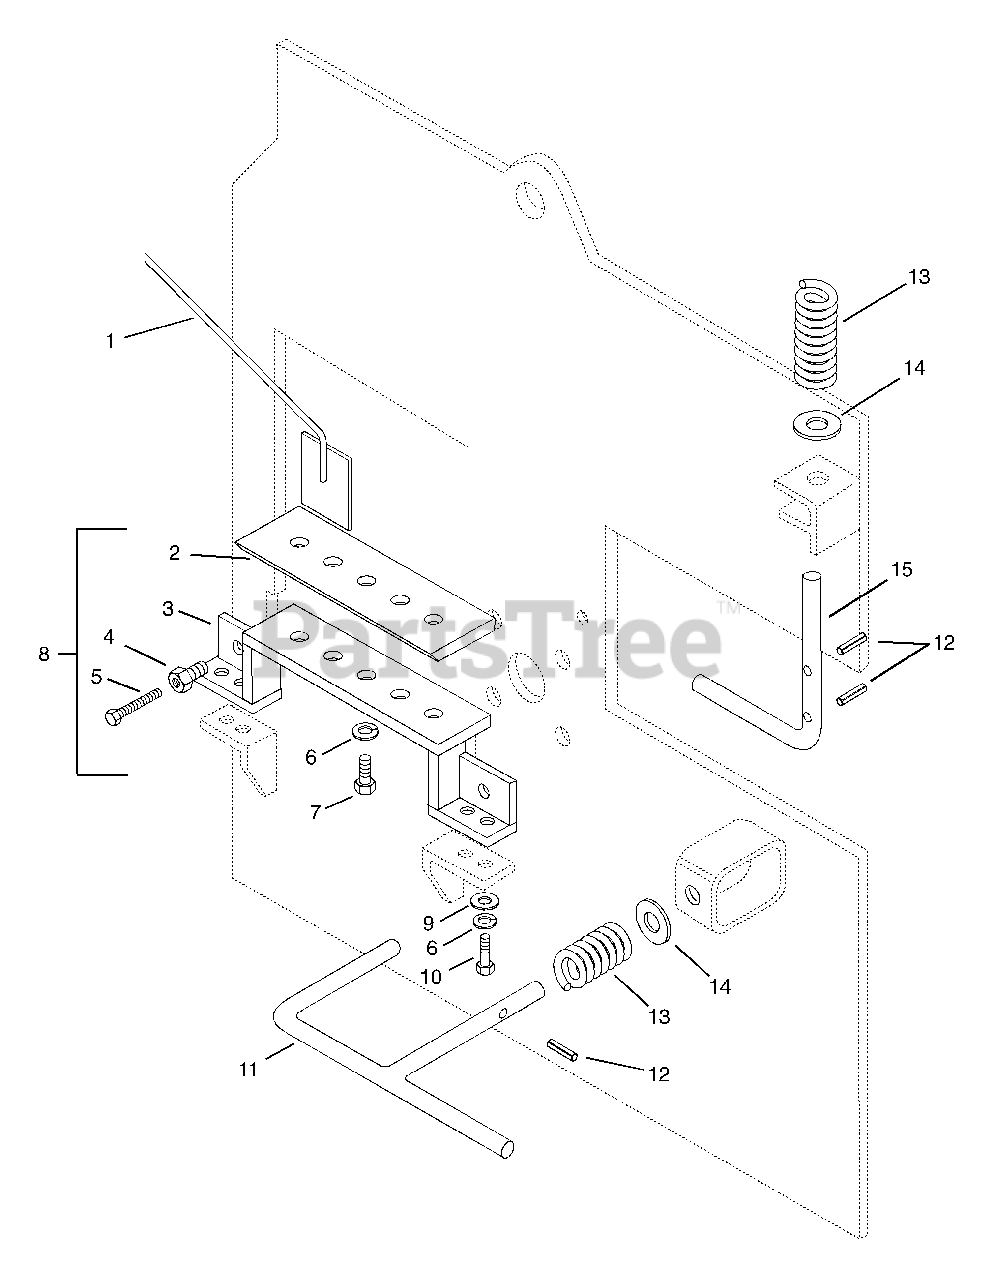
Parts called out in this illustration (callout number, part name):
1	Gauge-Knife
3	Mount-Bed Knife Weldment
4	Adjustment-Bed Knife
5	Bolt-Hex .38-16 x 2.25 Grade 5
6	Washer-Locking .50 x .125
7	Bolt-Hex .50-13 x 1.25 Grade 8
8	Bed Knife Kit
9	Washer-Flat-Steel .531 x 1.06 x .095
10	Bolt-Hex .50-13 x 1.25 Grade 5
11	Lock-Flywheel Weldment
12	Pin-Roll .188 x 1.50
13	Spring-Compression .080 x .91 x 3.38
14	Washer-Flat-Steel .688 x 1.75 x .134
15	Detent Pin
